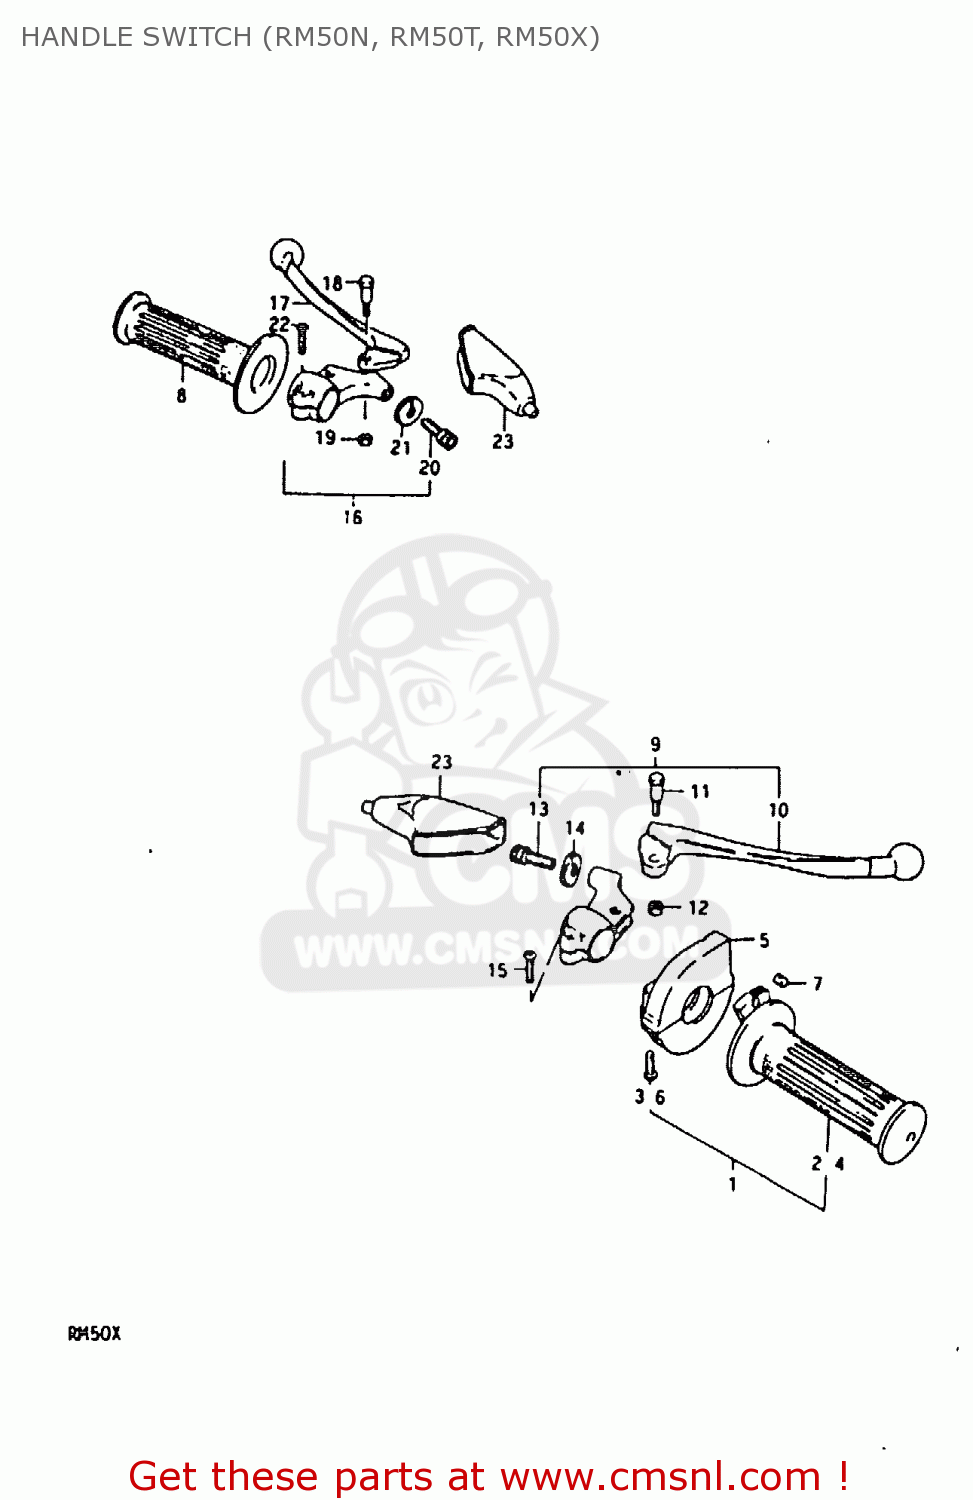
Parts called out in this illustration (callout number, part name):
1	CASE ASSEMBLY,THROTTLE
2	GRIP,THROTTLE
3	SCREW
4	GRIP,THROTTLE
5	CASE ASSY,THROTTLE
6	SCREW
7	PIECE,THROTTLE END
8	GRIP,L
9	LEVER ASSEMBLY,BRAKE
10	LEVER,BRAKE
11	BOLT,LEVER
12	NUT 6MM
13	ADJUSTER,CABLE
14	NUT,CABLE ADJUSTER
15	SCREW
16	LEVER ASSY,CLUTCH
17	LEVER,CLUTCH
18	BOLT,LEVER
19	NUT 6MM
20	ADJUSTER,CABLE
21	NUT,CABLE ADJUSTER
22	SCREW
23	COVER,CLUTCH LEVER
